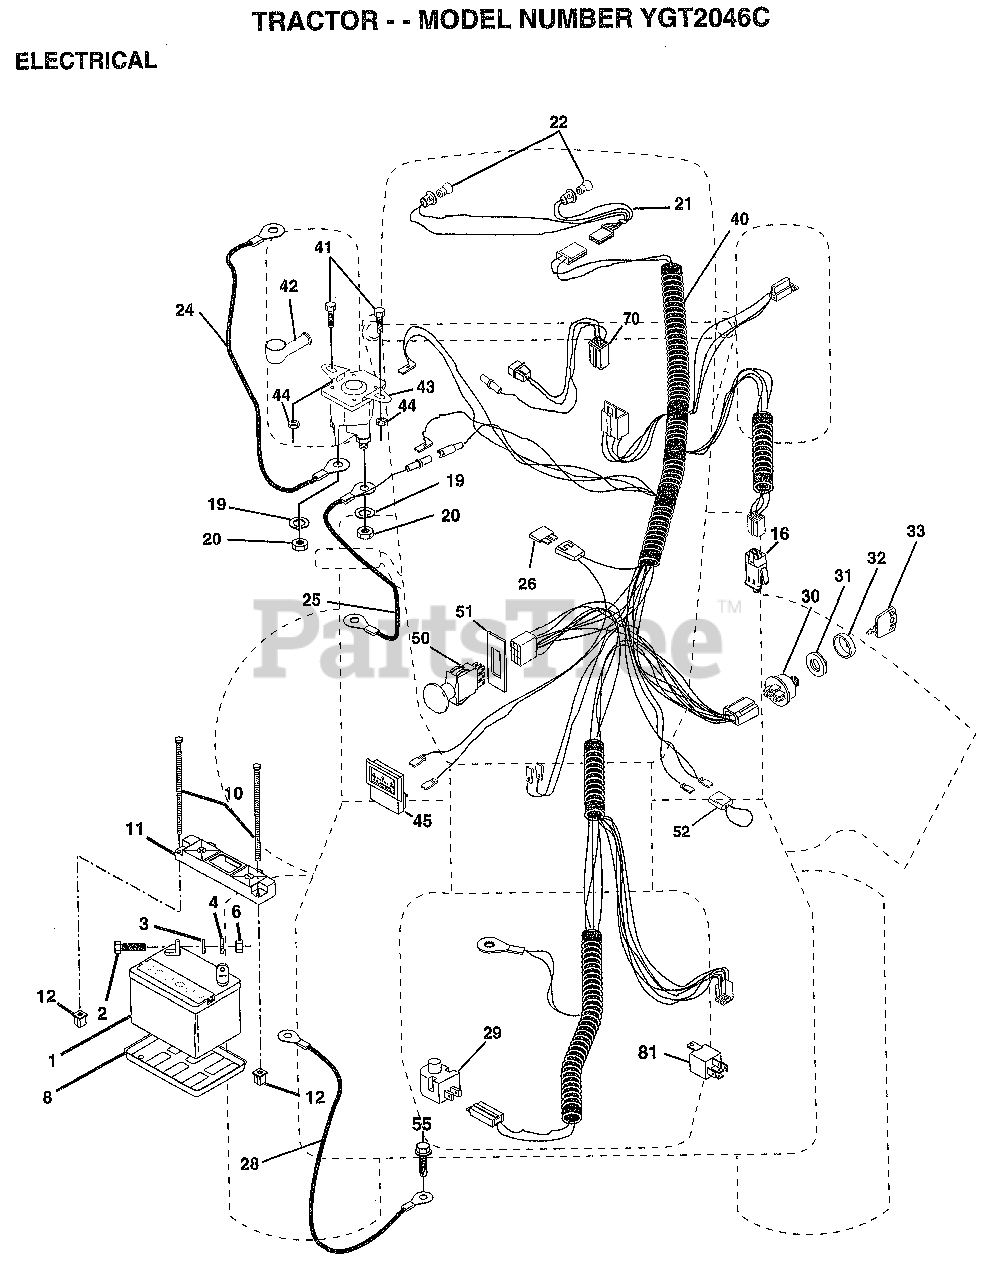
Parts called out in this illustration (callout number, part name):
3	WASHER
4	LOCKWASHER
8	"TRAY T, BATTERY"
11	HOLDDOWN BATTERY
16	SWITCH INTERLOCK
20	NUT
21	HARNESS.ASM.HDLIG
22	HEADLAMP BULB
24	CABLE-BATTERY T
25	CABLE.6GA.22W/16W
26	FUSE HYT
28	CABLE.GRND.6GA.21
29	SWITCH.PLUNGER
30	SWITCH IGN 4POS
31	NUT IGNITION
32	COVER KEY SWITCH
33	KEY
40	IGNITION HARNESS
41	BOLT HXHD FIN
44	NUT HXKEP 1/4X20
45	AMMETER
50	PTO SWITCH.BLK
51	RING RETAIN PTO
52	PROTECTION LOOP
70	HARNESS.ENG.B&S
81	RELAY ASSY T
